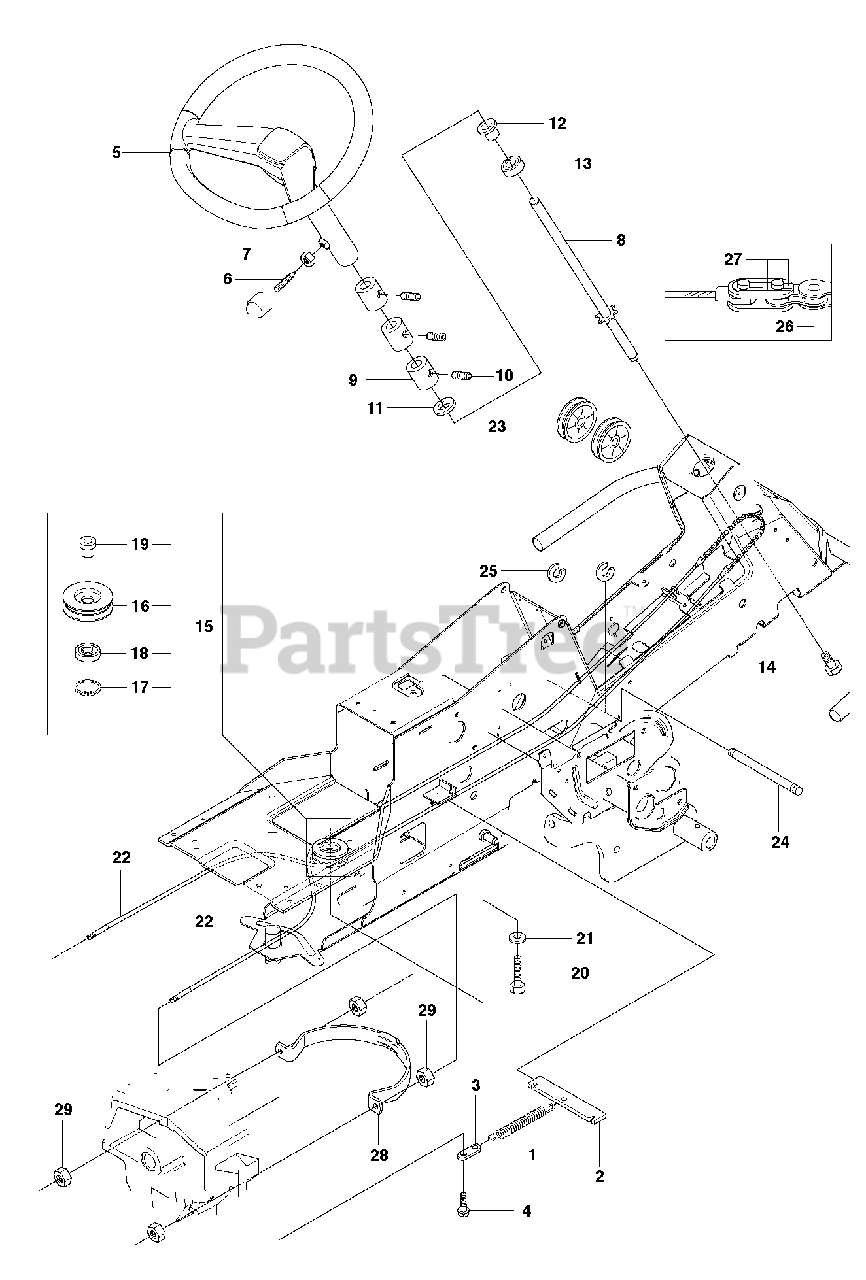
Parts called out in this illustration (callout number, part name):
2	SPRING BRACKET
3	CONNECTOR
5	STEERING WHEEL
7	NUT
8	ROD STEERING ASSY
13	BALL BEARING 6004-2RS1
16	ROLLER
17	CIRCLIP SGH 47
18	BALL-BEARING 6204-2RS
19	BUSHING
20	COLLAR SCREW
22	RP STEERING CABLE COMPLETE
25	RETAINING RING
26	STEERING CHAIN
28	WIRE GUIDE
